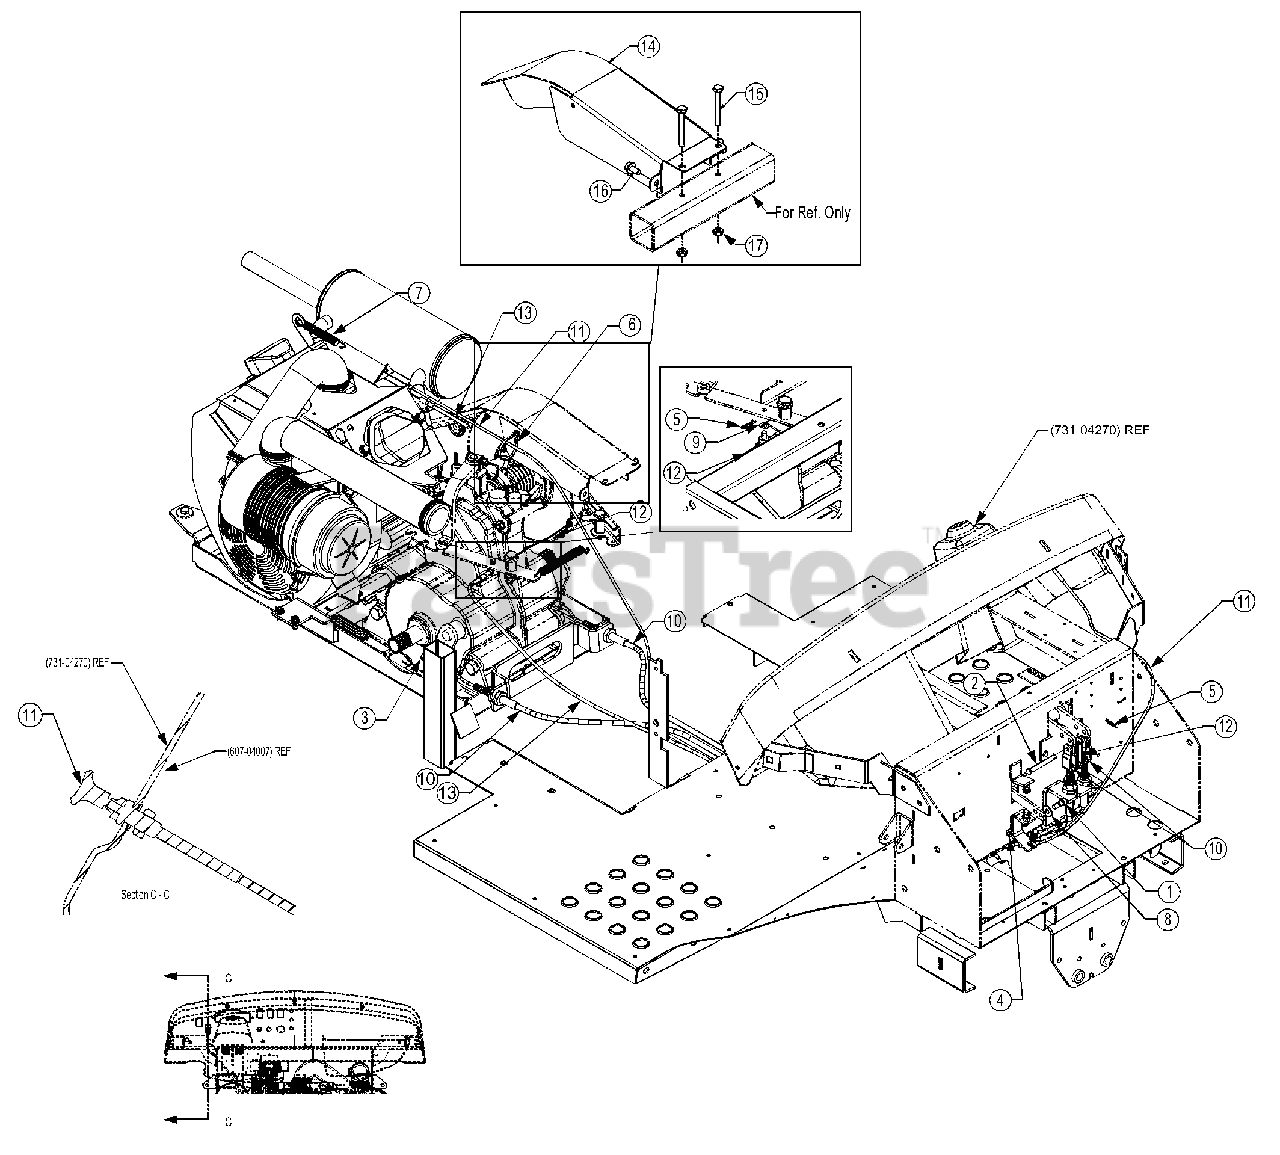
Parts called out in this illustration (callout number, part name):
1	Screw, Shoulder, .375 x .375
2	Pin, Clevis, 5/16 x 2.5
3	Nut, Jam 5/16-18
4	Nut, Hex Lock, 5/16-18
5	Pin, Cotter, .072 x 1.13
6	Tie, Cable 19 x 8.39 Tree Mount
7	Extension Spring,.530 OD x 4.75 LG
8	Washer, .349 x .879 x .063
9	Washer, Spring.317 ID x.625 OD
10	Cable, Control Brake
11	Cable, Control, Choke
12	Cable, Control Brake Clutch
13	Cable, Control, Throttle
14	Guard, Belt
15	Screw, Hex 5/16-18 x 2.5
16	Screw, Flange 5/16-18 x.625
17	Nut, Hexlock 5/16-18
